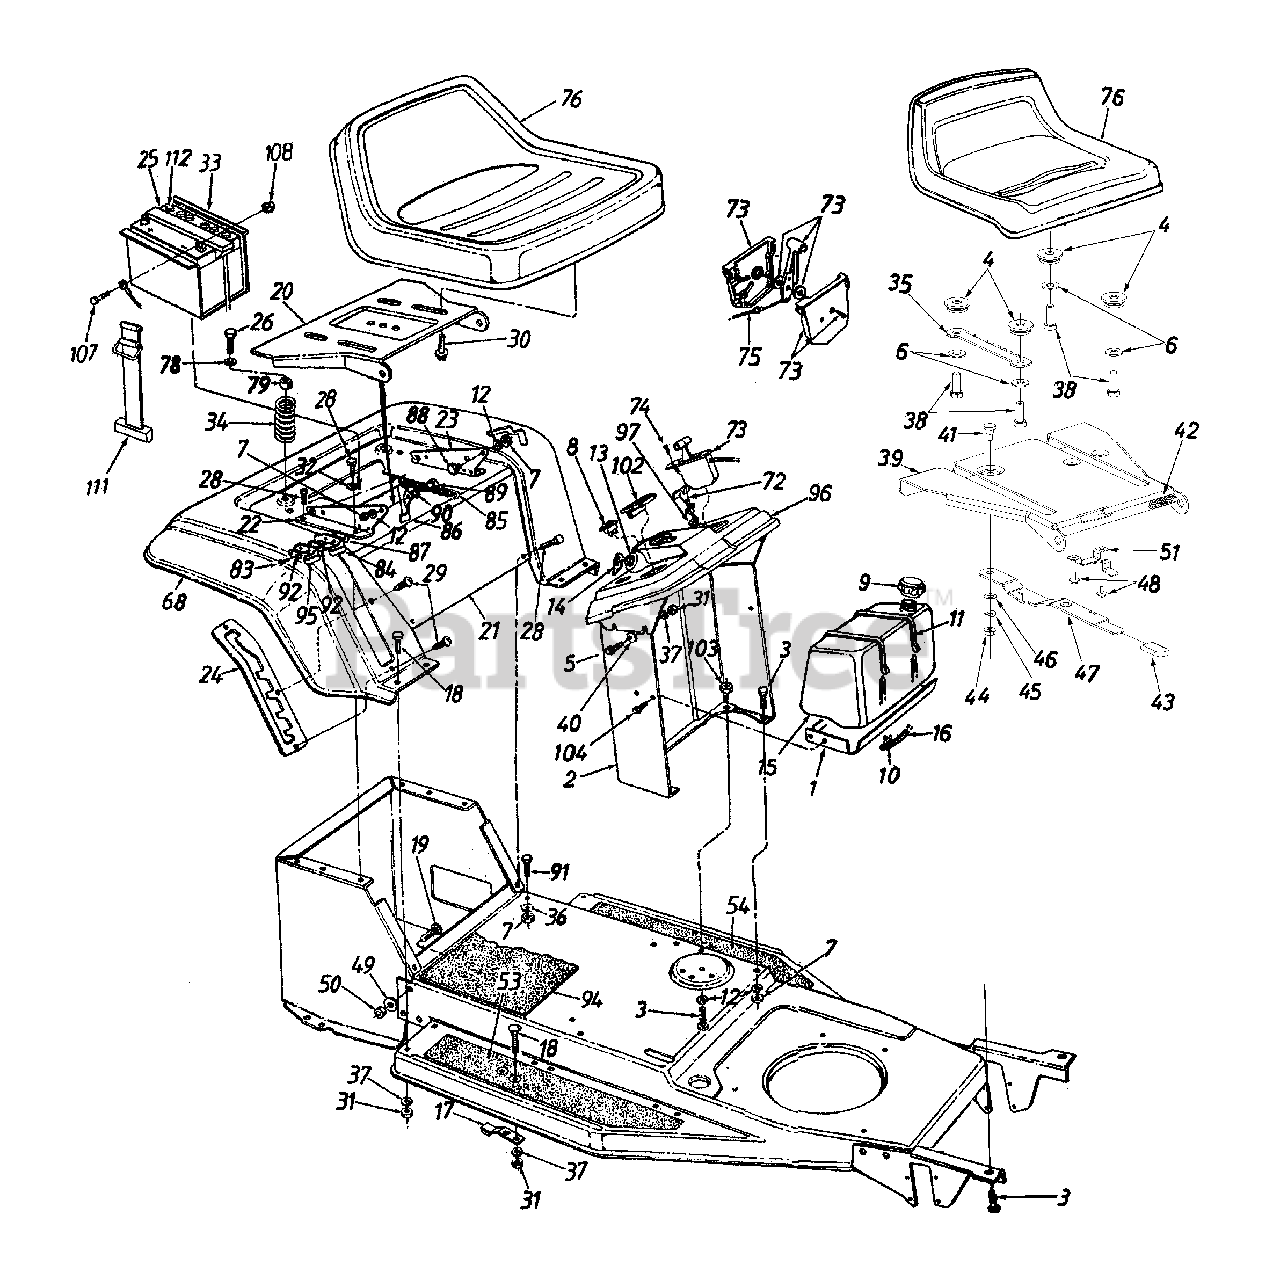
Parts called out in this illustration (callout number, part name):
4	Spacer
5	Hex Bolt 1/4 x .62" Lg.
6	Fl-Wash. .406" I.D. x .875" O.D.
7	Hex Nut 5/16-18 Thd.
8	Light Switch
9	Gas Cap
10	Hose Clamp
11	Cable Tie
12	Lock Washer 1/4" I.D.
13	Ignition Switch: 5 Pin
14	Ignition Key
15	Fuel Tank
16	Gas Line 15" Long
17	Blade Brake Ass'y.
18	Carriage Bolt 1/4-20 x .62"
19	Ribbed Neck Bolt 3/8-24 x .8"
25	Battery, Dry
26	Hex Self-Tap Screw 5/6-18 1.25" Lg.
28	Hex AB-Tap Scr. 5/16 x .75" Lg.
29	Torx Mach. AB-Tap Scr.
30	Hex Self-Tap Scr. 3/8-16 x.62"
31	Hex Nut 1/4-20 Thd.
32	External Lock Washer 5/16" I.D.
35	Seat Selector
36	Bell-Washer 5/16" I.D.
37	Lock Washer 1/4" I.D.
38	Hex Bolt 3/8-16 x 1" Lg.
41	Shld. Bolt .34" x 1/4-20 Thd.42
42	Compression Spring
43	Seat Adjustable Grip
44	Hex Flanged L-Nut 1/4-20 Thd.
45	Spring Wash. .265" I.D.
46	Fl-Wash. .344" I.D.
47	Seat Lever
48	Hex Wash. Hd. B-Tap Scr.
49	Lock Washer 3/8" I.D.H.D.
50	Hex Lock Nut 3/8-24 THd.
51	Seat Stop
53	Foot Pad-R.H. (Abrasive)
54	Foot Pad-L.H. (Abrasive)
68	Trim Strip 81" Lg.
72	Choke Control
73	Throttle Control Box
74	Truss AB-Tap Scr. #10 x .5"
75	Throttle Wire (B&S)
76	Seat Assembly (Low Back)
78	Flat Washer .344" I.D. x .88" O.D.
79	Bushing
83	Hex Tap Scr. #8 x .5" Lg.
84	Safety Switch (Inner)
85	Ext. Spring 5.31" Lg.
86	Seat Lift Brkt.
87	Insulator Boss Plate
88	Shld. Bolt .437" Dia. x .162" Lg.
89	Shld. Bolt .437" Dia. x .268" Lg.
90	Spring Washer .445" I.D. x .75"
91	Hex Washer Hd. Scr.
92	Insulator Plate
94	Center Foot Pad (Abrasive)
95	Safety Switch (Outer)
96	Dash Panel (w/Amp & Light switch)
97	Retainer Clip
102	Ammeter
103	Hex Jam Nut 5/16-18 Thd.
104	Hex Washer Hd. Tap Scr.
107	Hex Bolt 1/4-20 x .75" Lg.
108	Hex Sems Nut 1/4-20 Thd.
111	Battery Strap
112	Battery Cap
